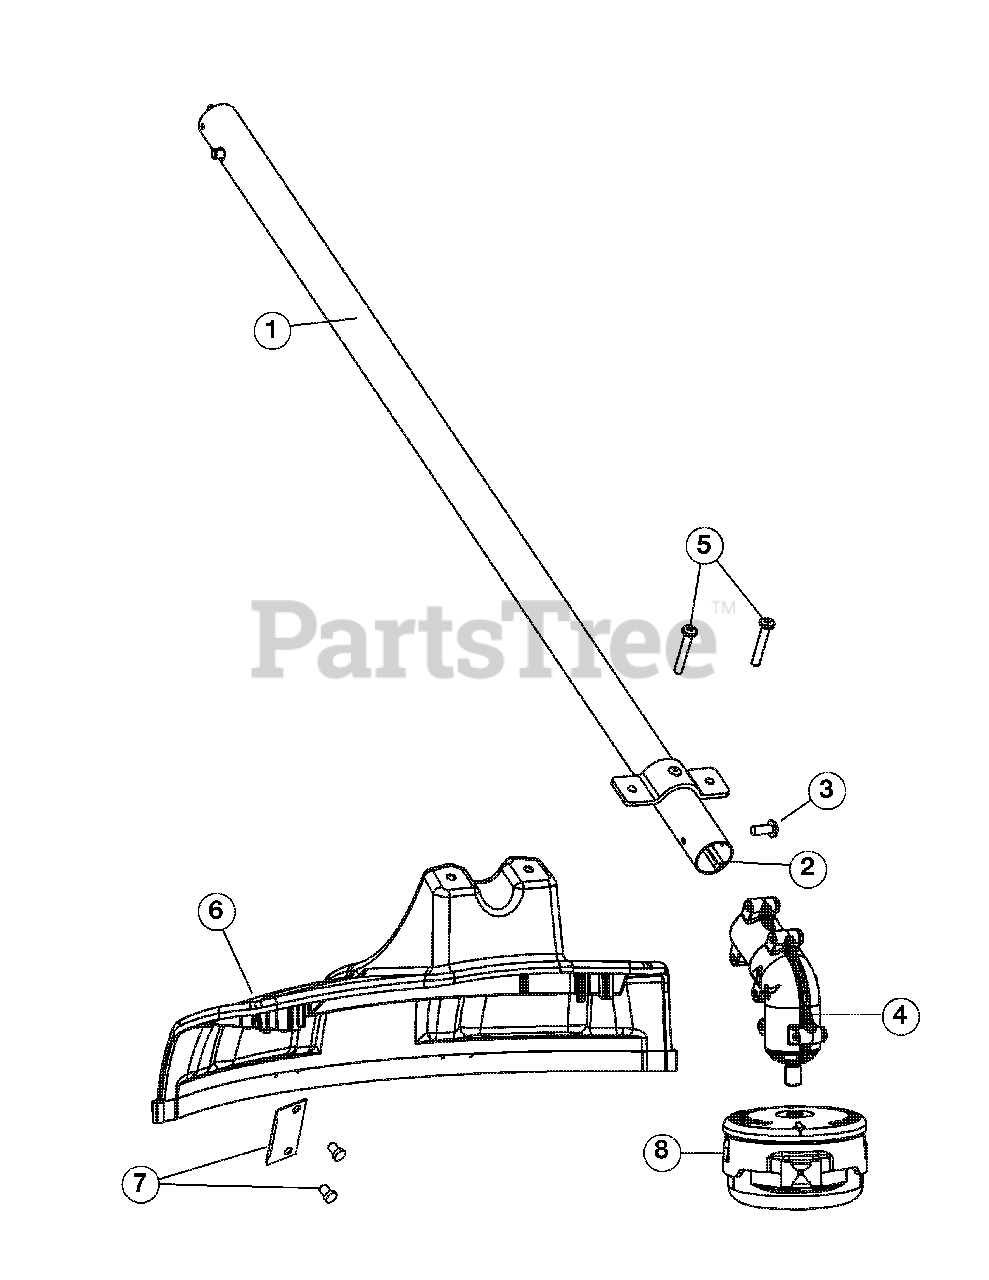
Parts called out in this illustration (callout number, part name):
1	Lower Drive Shaft Housing Assembly
2	Lower Flexible Drive Shaft
3	Anti-Rotation Screw
4	Gear Box Assembly (includes 3)
5	Shield Mounting Screws
6	Shield Assembly (includes 5 & 7)
7	Blade Assembly
8	Cutting Head Assembly
